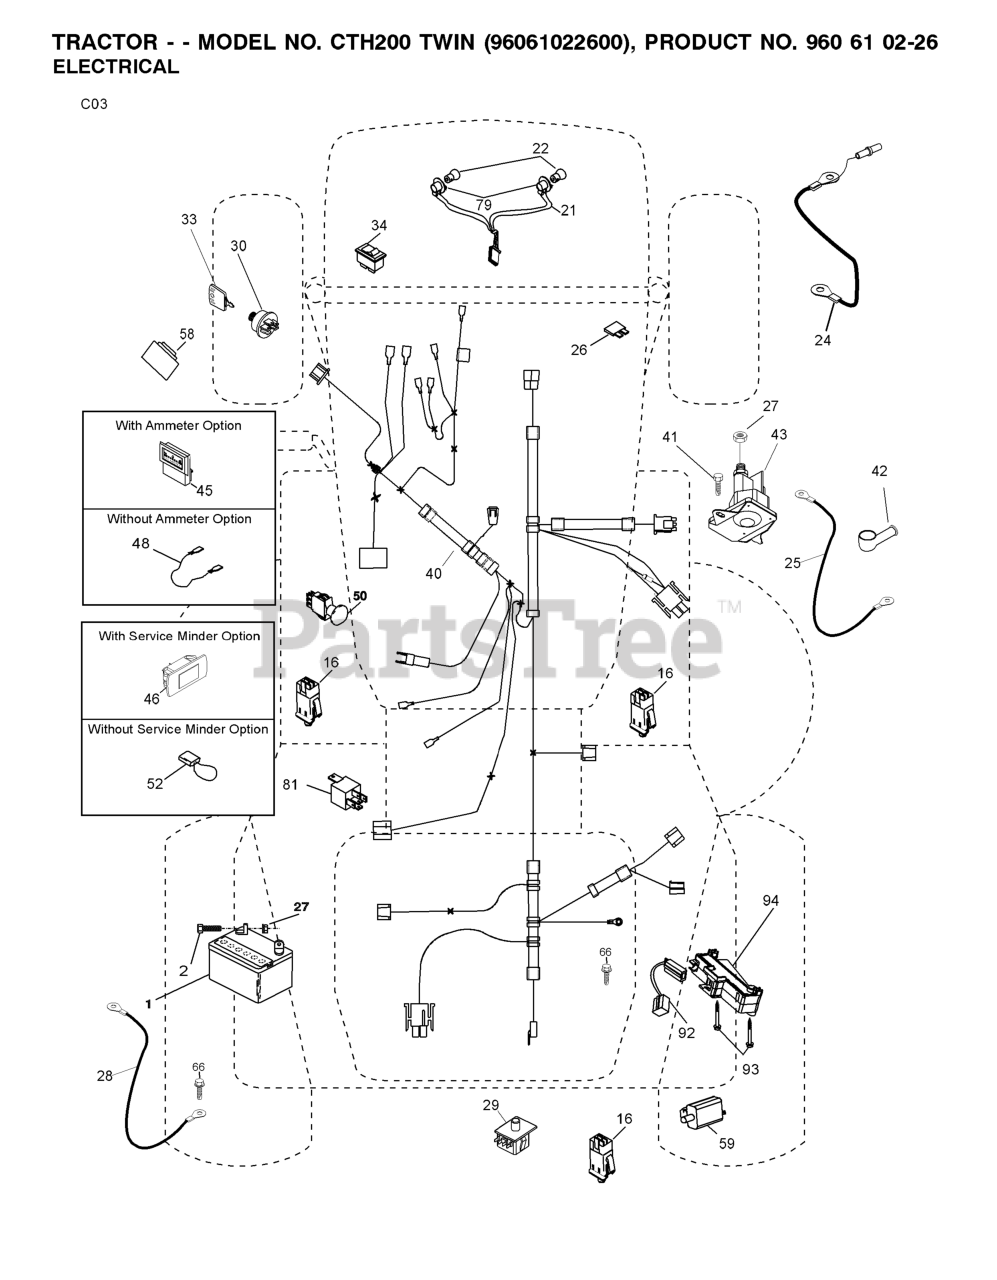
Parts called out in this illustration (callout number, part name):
1	Battery 12 Volt 25 Amp
2	BOLT.HEX.1/4.X.3/4.DICHROMATE
16	SWITCH INTERLOOK PUSH-IN
21	HARNESS ASSY LIGHT
24	CABLE.BATTERY.6GA.16"RED
25	CABLE BATTERY
26	FUSE 20AMP
27	NUT
28	CABLE GROUND
29	SWITCH.SEAT.DP W/RAMPS
30	SWITCH.IGN.DELTA.W.LGH.ROS
33	KEY.CHAIN.BLISTER.PACK.GEN.INT
40	RP HARNESS.IGN.ELECT.REG.CRD
41	BOLT
42	TERMINAL COVER
43	SOLENOID.W/BRASS.PLUNGER
48	ADAPTER.AMMETER
50	RP.PTO.SWITCH.8 TERMINAL.BLACK
58	BUZZER
59	.WITCH.FULL BAGGER.INDICATOR
79	BULB HOLDER ASM.
81	RELAY.ASSY.T
92	HARNESS.PIGTAIL.CONSLE
93	SCREW.PLASTITE
94	MODULE.REVERSE.ROS
